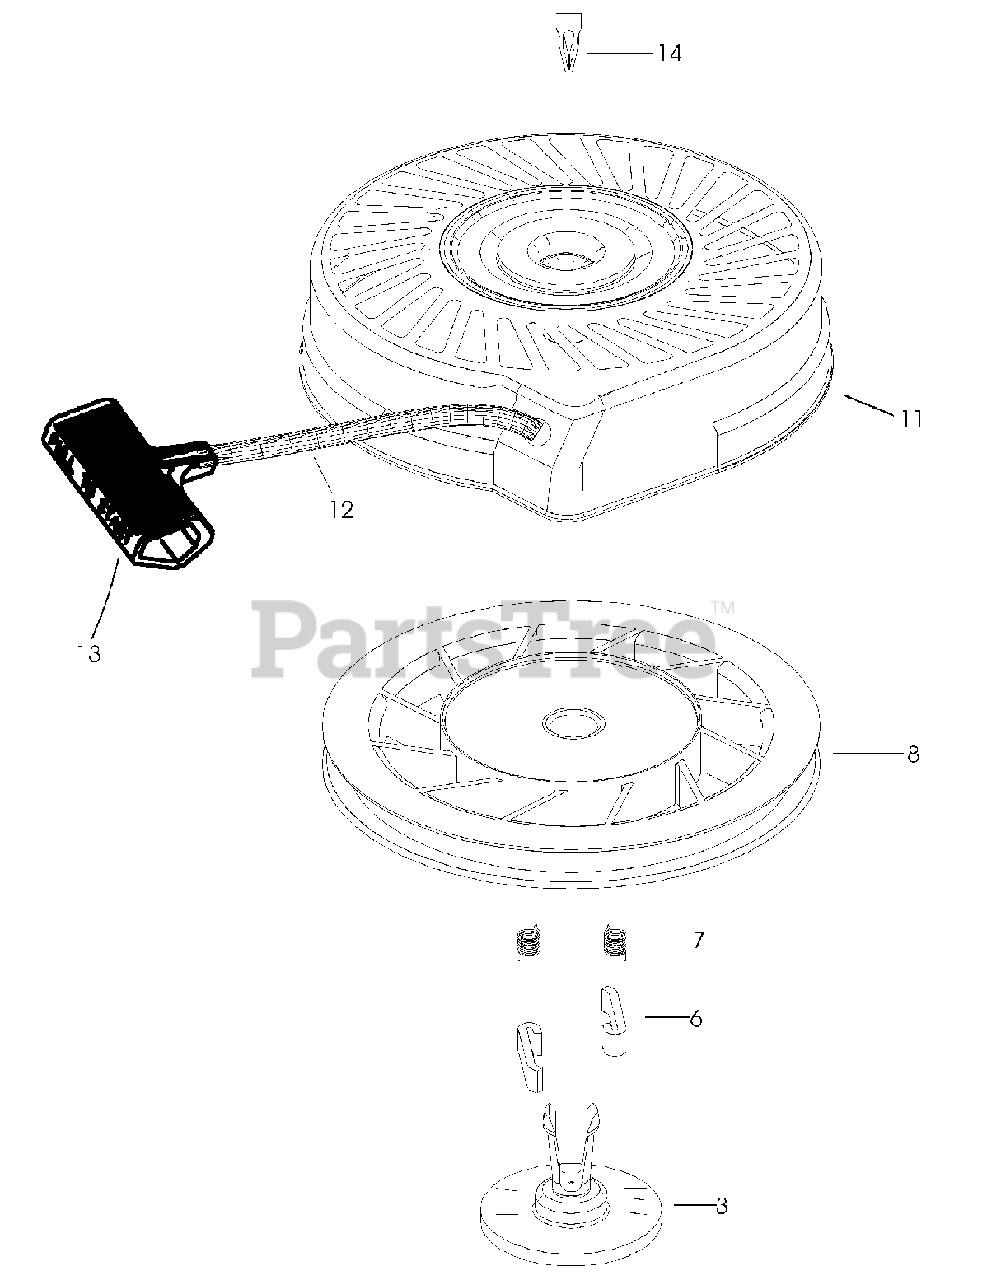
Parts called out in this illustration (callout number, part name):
3	Retainer
6	Dog-Starter
7	Dog Spring
8	Pulley & Rewind Spring ASM
11	Starter Housing ASM (40 degree grommet)
12	Rope Starter
13	Handle-Starter
14	Cup Washer
